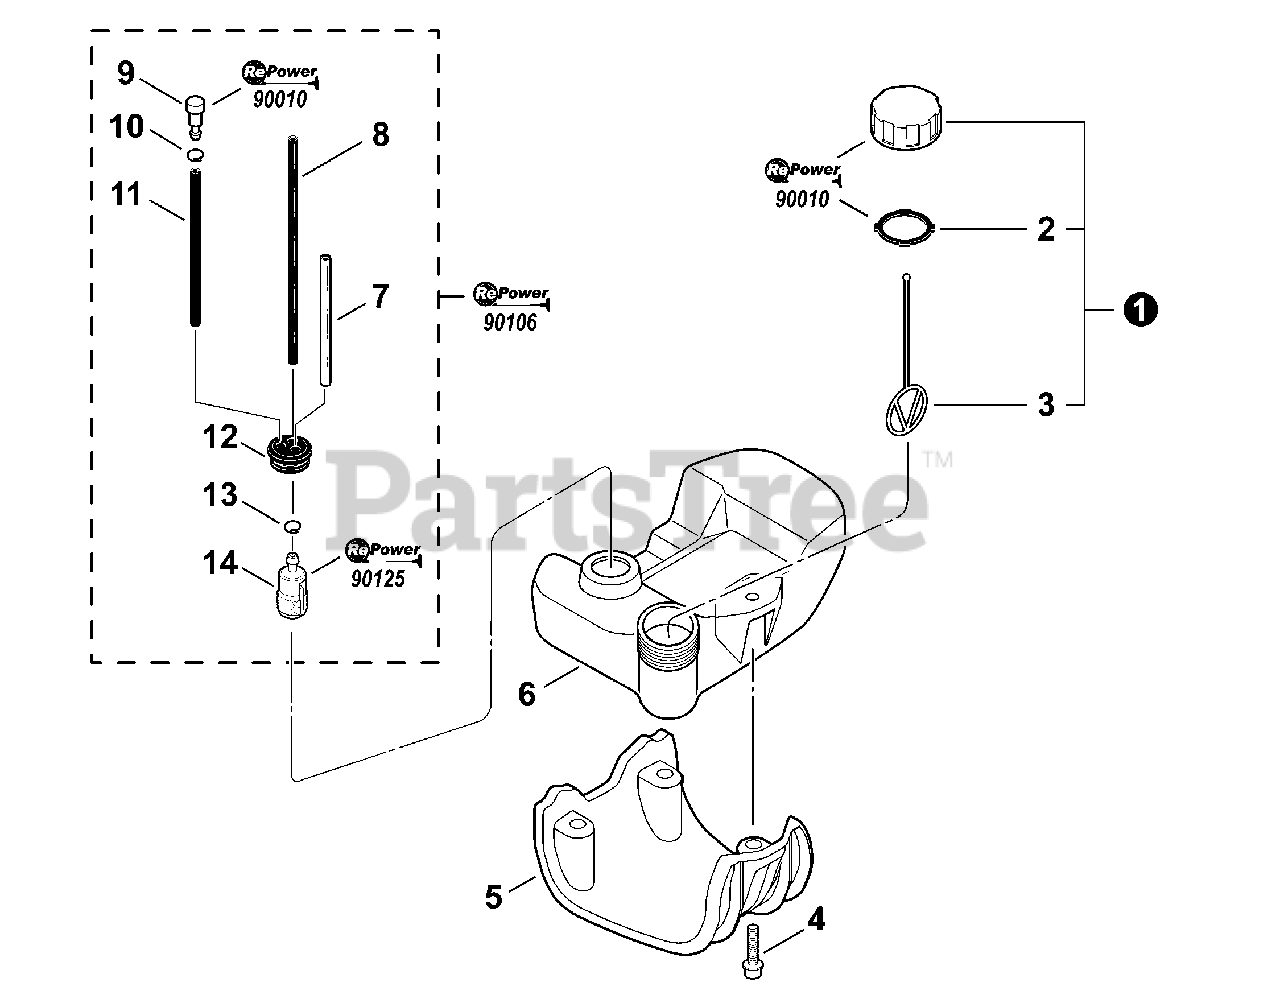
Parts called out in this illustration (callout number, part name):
1	CAP ASSY, FUEL
2	GASKET, FUEL CAP
3	CONNECTOR, CAP L= 100 MM
4	BOLT 5×20
5	GUARD, FUEL TANK
6	TANK, FUEL
7	PIPE, FUEL 3×6×80 CLEAR
8	PIPE, FUEL 3×5×195 BLACK
9	VENT ASSY
10	CLIP 6.5 MM
11	PIPE 3×6×115 BLACK
12	GROMMET, FUEL
13	CLIP 6 MM
14	FILTER, FUEL 125-528
